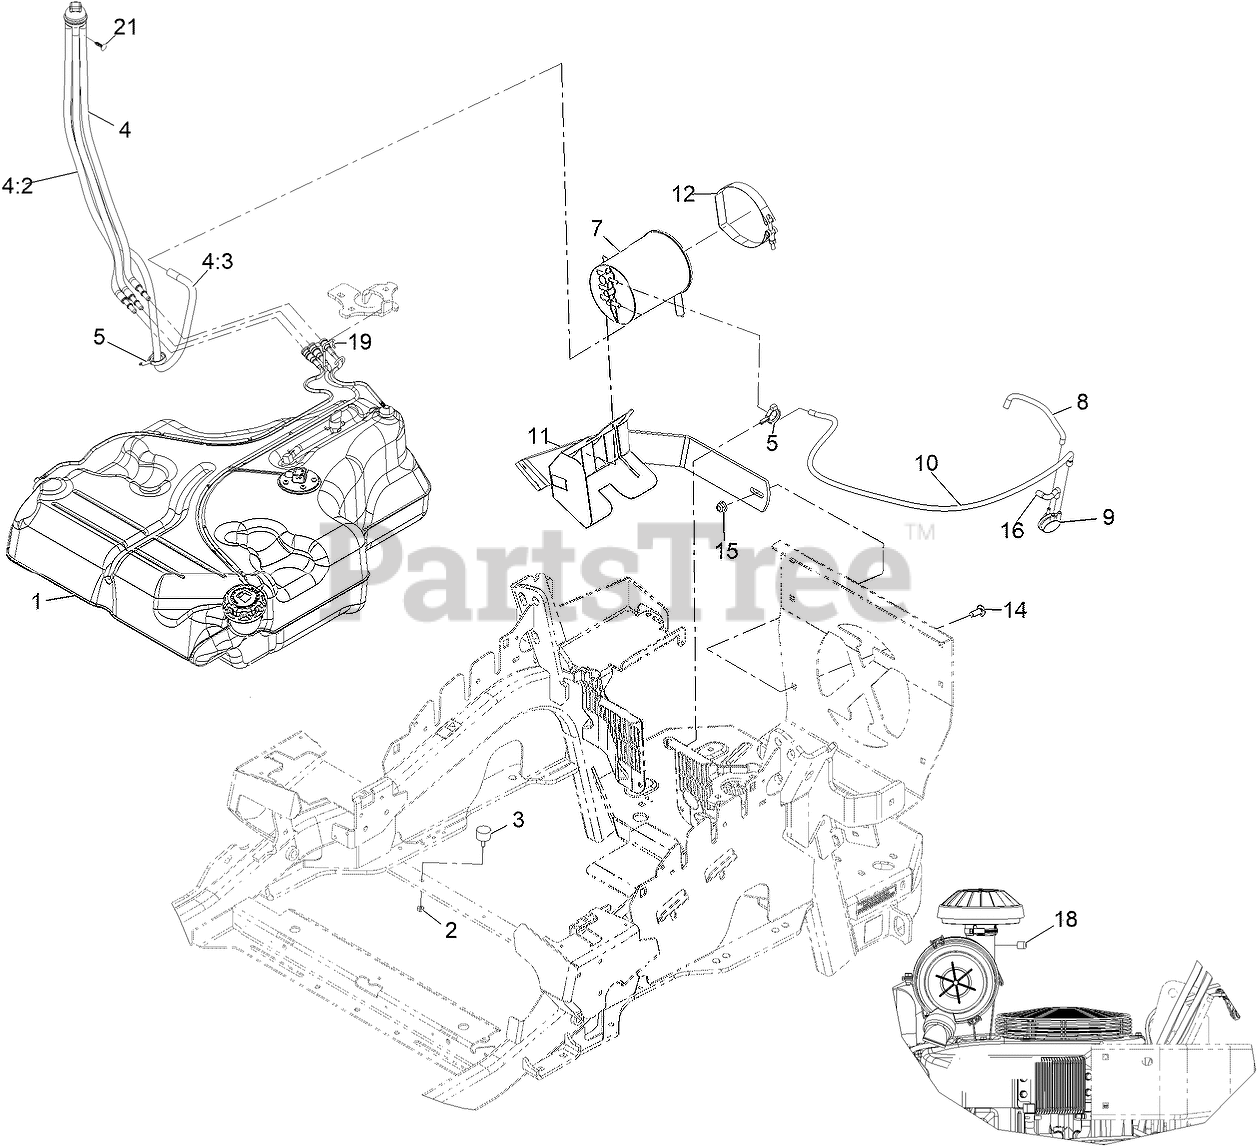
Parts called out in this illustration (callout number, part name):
1	ASM-8 GALLON FUEL TANK
2	NUT-JAM
4	FUEL MANIFOLD VENT ASM
4:2	HOSE-FUEL
4:3	HOSE-FUEL
5	CLAMP-HOSE
7	CANISTER-CARBON, 1200CC
8	HOSE-VENT,FORMED
9	VALVE-CONTROL, VACUUM
10	HOSE,VENT,FORMED
11	MOUNT-CANISTER
12	CLAMP, T-BOLT
14	SCREW-CARR
15	NUT-HF, NI
16	HOSE-VENT, FORMED
18	PLUG-PORT
19	RETAINER-LINE, VAPOR
21	PLUG-PLASTIC
